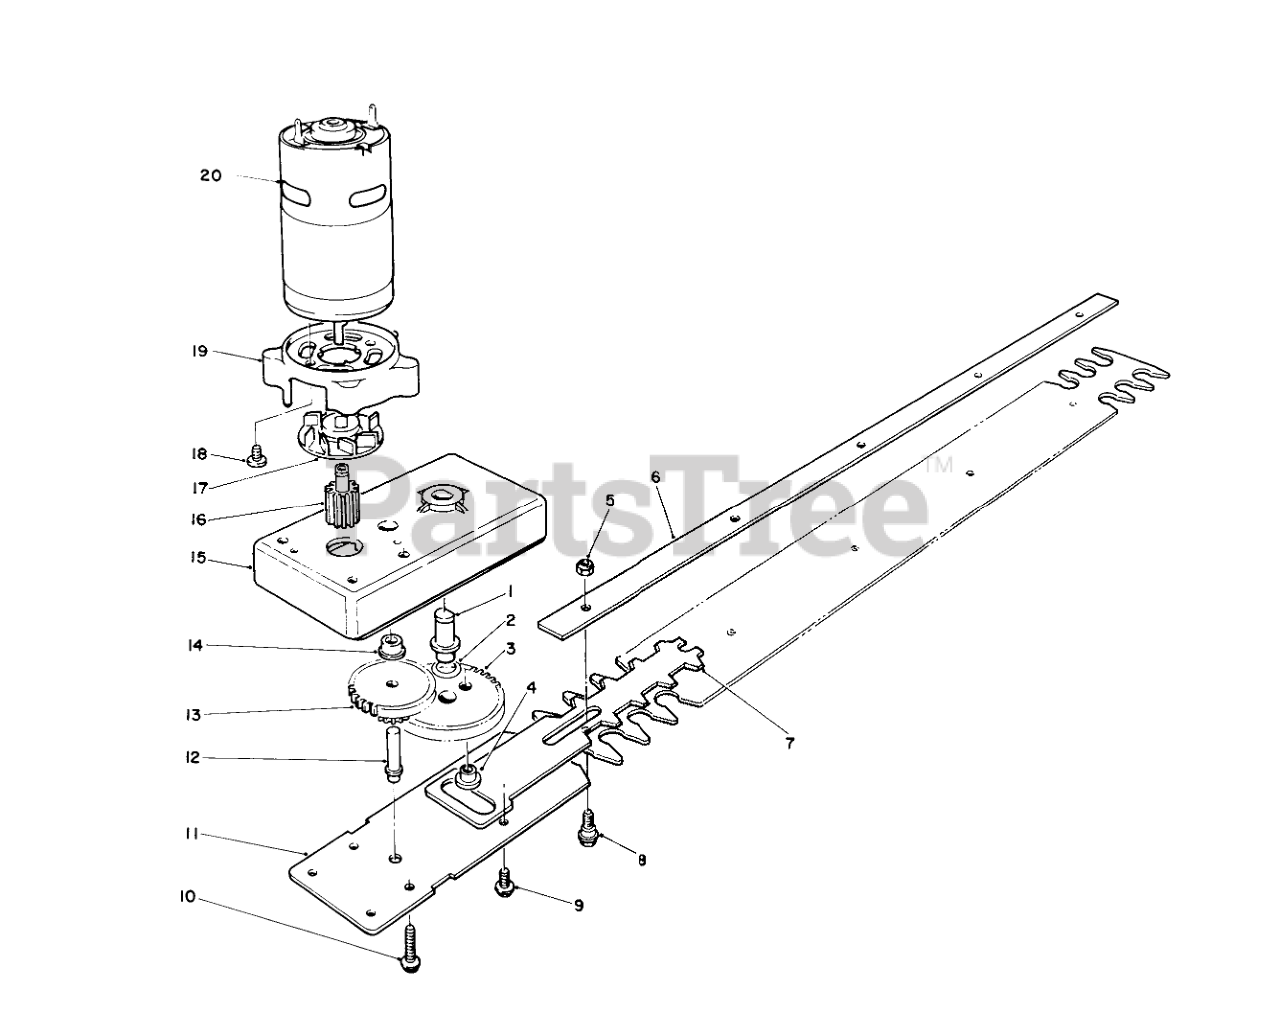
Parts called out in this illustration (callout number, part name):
1	Shaft-Driver
2	WAVE-DRIVER
3	GEAR-DRIVE
4	GEAR BUSHING
5	NUT-LOCK
6	RETAINER BLADE
7	Blade-Cutting
8	BLADE BOLT
9	SCREW-PPHTF
10	SCREW - #8 X 1-1/4
11	Blade-Bottom
12	SHAFT-IDLER
13	GEAR-IDLER
14	Bearing-Idler
15	Housing (Incl.Ref.#1&14)
16	Gear-Motor
17	Fan-Motor
18	Screw-Phillips Hd. Pan
19	Support-Motor
20	Motor (Incl.Ref.#16-19)
